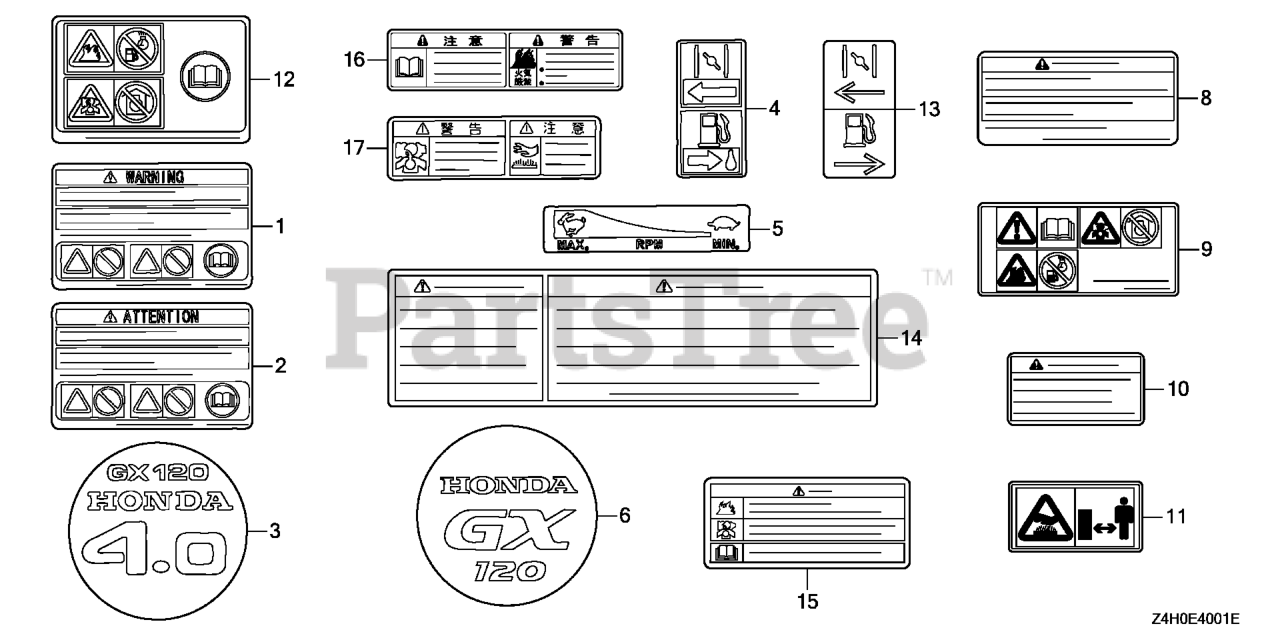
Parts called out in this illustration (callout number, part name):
8	MARK, OPERATOR CAUTION (ENGLISH)(MADE IN THAI)
8	MARK
8	MARK, OPERATOR CAUTION (FRENCH)(MADE IN THAI)
10	MARK, EX. CAUTION (ENGLISH)
10	MARK, EX. CAUTION (FRENCH)
